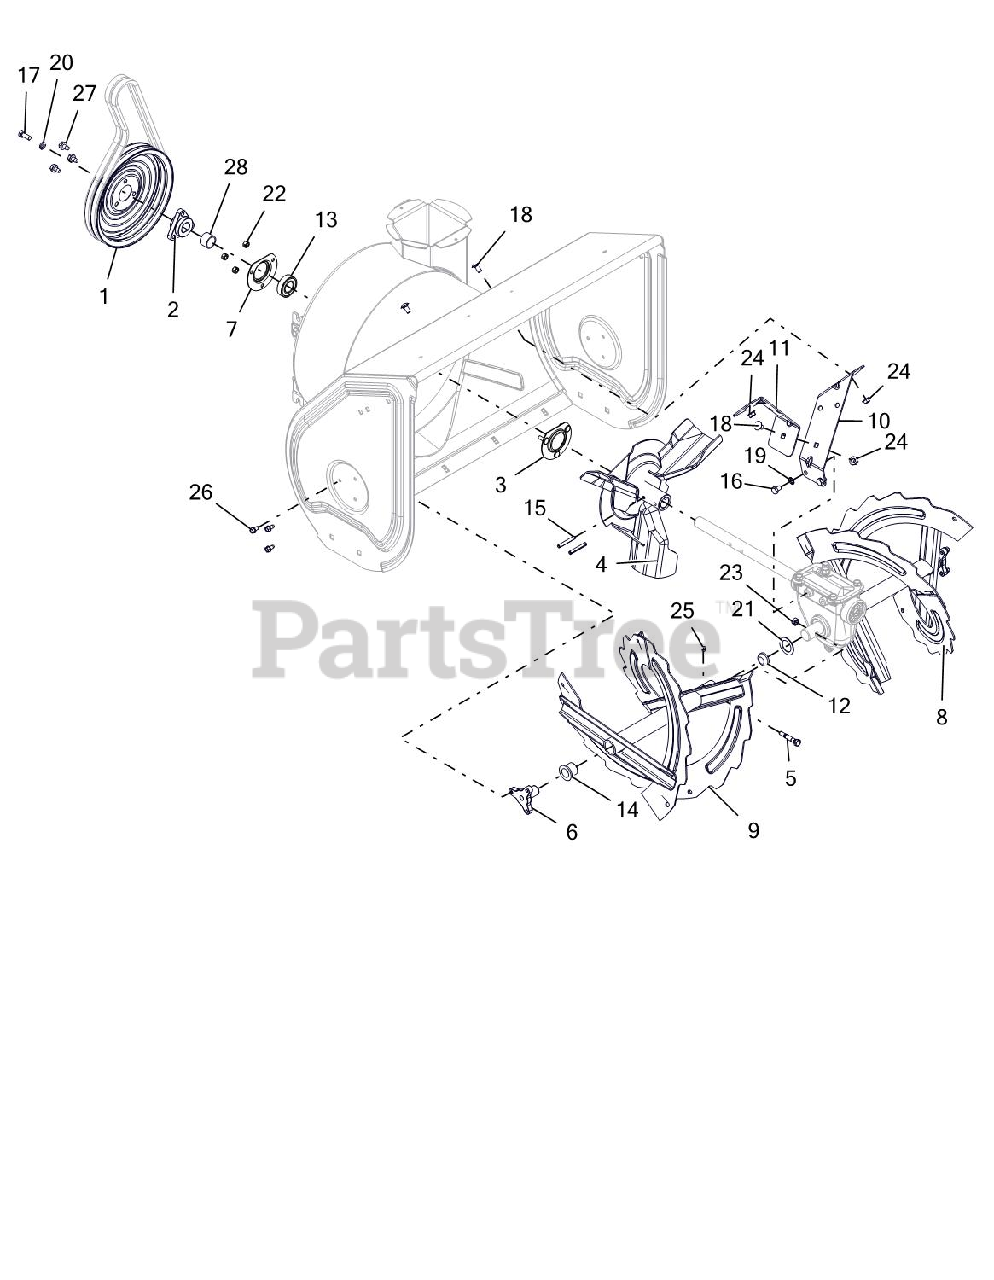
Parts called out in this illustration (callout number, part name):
1	PULLEY, SPIN FORM DUAL GROOVE
2	PULLEY HUB, D-BORE .87 DELUXE
3	BEARING FLANGE
4	IMPELLER, 3 BLADE-14"
5	SHEAR BOLT SERVICE ASSEMBLY
6	SUPPORT, RAKE BUSHING
7	BEARING FLANGE
8	RAKE, LH W/ZERK - 28"
9	RAKE, RH W/ZERK - 28"
10	BRACKET, GEARCASE SUPPORT - LH
11	BRACKET, GEARCASE SUPPORT - RH
12	PLUG, RAKE TUBE
13	BRG-BALL .876X1.75X.50 RSTFP
14	BSHG-FLG, NY.778 ID X 1.018 OD
15	PIN-ROLL .250X1.75
16	@BLT-HEX .31-18X.50 GR5 YWZC
17	BLT-HEX .31-24X.75 YWZC GR5
18	BLT-RDHDSQSHNK.31-18X.62 YZ-LK
19	@WSHR-LK-EXT.326X.599X.031YWZC
20	WSHR-LK .312X.097 HVY YWZC
21	WSHR-FL-STL 1.010X1.505X.062YZ
22	@NUT-LK-CTR .25-20 YWZC
23	@NUT-LK-CTR .31-18 YWZC
24	@NUT-LK-TOP-FLG .31-18 YWZC
25	ZERK,FITTING .25X.125 DRIVE IN
26	SCR-TAP .25-20X.50 HWH TR YWZ
27	@SCR-TAP .31-18X.50 HWH TR YWZ
28	BSHG,SPCR .895X1.065X.693
